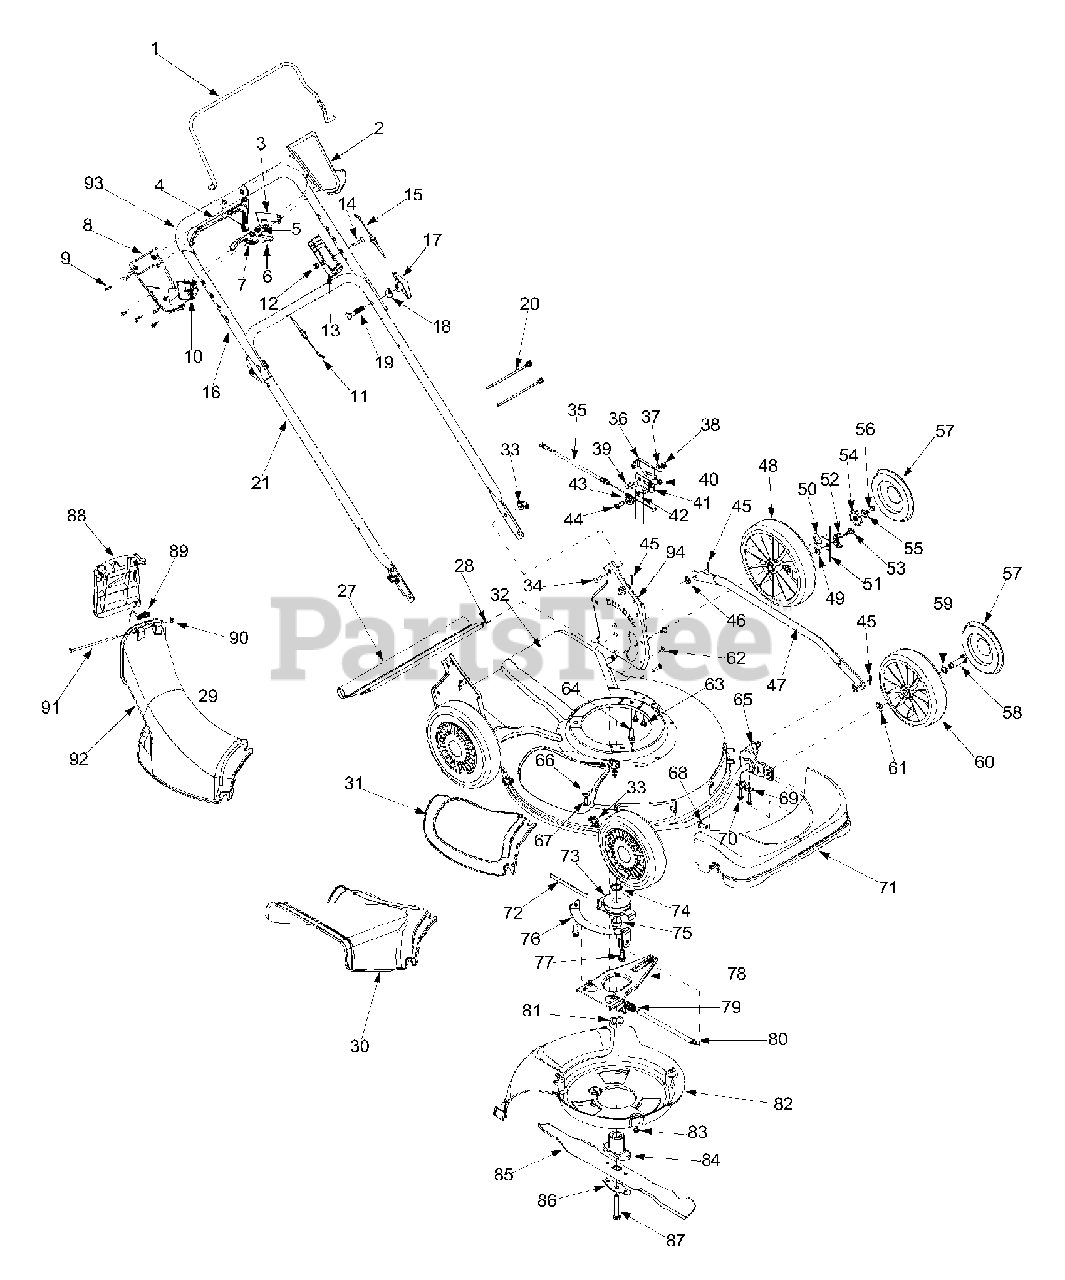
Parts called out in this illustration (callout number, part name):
1	Control Handle
2	Upper Control Handle
3	6 Spd. Rack Cable Bracket
4	Control Lever
5	Gear Insert
6	Shift Lever Spring
7	6 Speed Shift Lever
8	Lower Control Housing
9	C Sunk Tap Screw #10 x .75 Lg
10	Cable Mounting Cap
11	Drive Cable 51.0
12	Top Lock Nut 1/4-20
13	Control Housing
14	Oval C-Sunk Screw
15	Control Cable 46"
17	Wing Nut
18	Saddle Washer .320 ID x .830 OD
19	Carriage Bolt 5/16-18 x 2.0
20	Cable Tie
27	Trail Shield
28	Trail Shield Wire
29	Chute Assembly
30	Side Discharge Chute
31	Mulch Cover
33	Wing Nut
34	Carriage Bolt 1/4-20 x .75
35	6 Speed Cable
38	Hex Nut 1/4-20
39	Carriage Screw 1/4-20 x .50
40	Hex Nut 1/4-28
43	Roller Cable
44	Shoulder Screw .375 ID x 1/4-14
45	Cotter Pin
46	Bowed Washer
48	Wheel 9 x 2
49	Top Lock Tab Weld Nut 1/4-20
50	Ratchet Pawl Plate
51	Plastic Spring Ratchet
52	Pawl RH
53	Shld Screw .340 ID x .285 OD
54	Wheel Rachet
55	Bell Washer .265 ID x .75 OD
56	Hex Cap Screw 1/4-20 x .620
57	Hubcap
58	Shoulder Screw .498 x 1.445
59	Wave Washer .510 ID x .750 OD
60	Wheel 8 x 2
61	Spring Washer .401 ID x .870 OD
62	Screw 1/4-14 x .500
63	Screw 1/4-14 x .625
64	Hex Washer Screw 3/8-16 x 1.0
66	Flat Washer .344 ID x .62 OD
67	Carriage Screw 1/4-20 x .75
68	Torx Screw
69	Block Bushing
70	Hex Washer Screw
71	Front Axle Cover
72	Belt 3/8 x 39.24
73	Pulley Assembly
74	Sleeve Spacer .88 ID x 1.13 OD
75	Sleeve Spacer .88 ID x 1.00 OD
77	Screw 3/8-18 x 1.0
80	Pivot Shaft
81	Wave Washer 1.38 ID x .88 OD
82	Baffle
83	Screw 1/4-20 x 3.75
84	Blade Adapter Kit
85	21" Mulching Blade
86	Blade Bell Support
87	Hex Bolt 3/8-24 x 2.5
88	Chute Door
89	Torsion Spring
90	Push Cap
91	Pivot Rod
92	Discharge Chute
93	Grip
